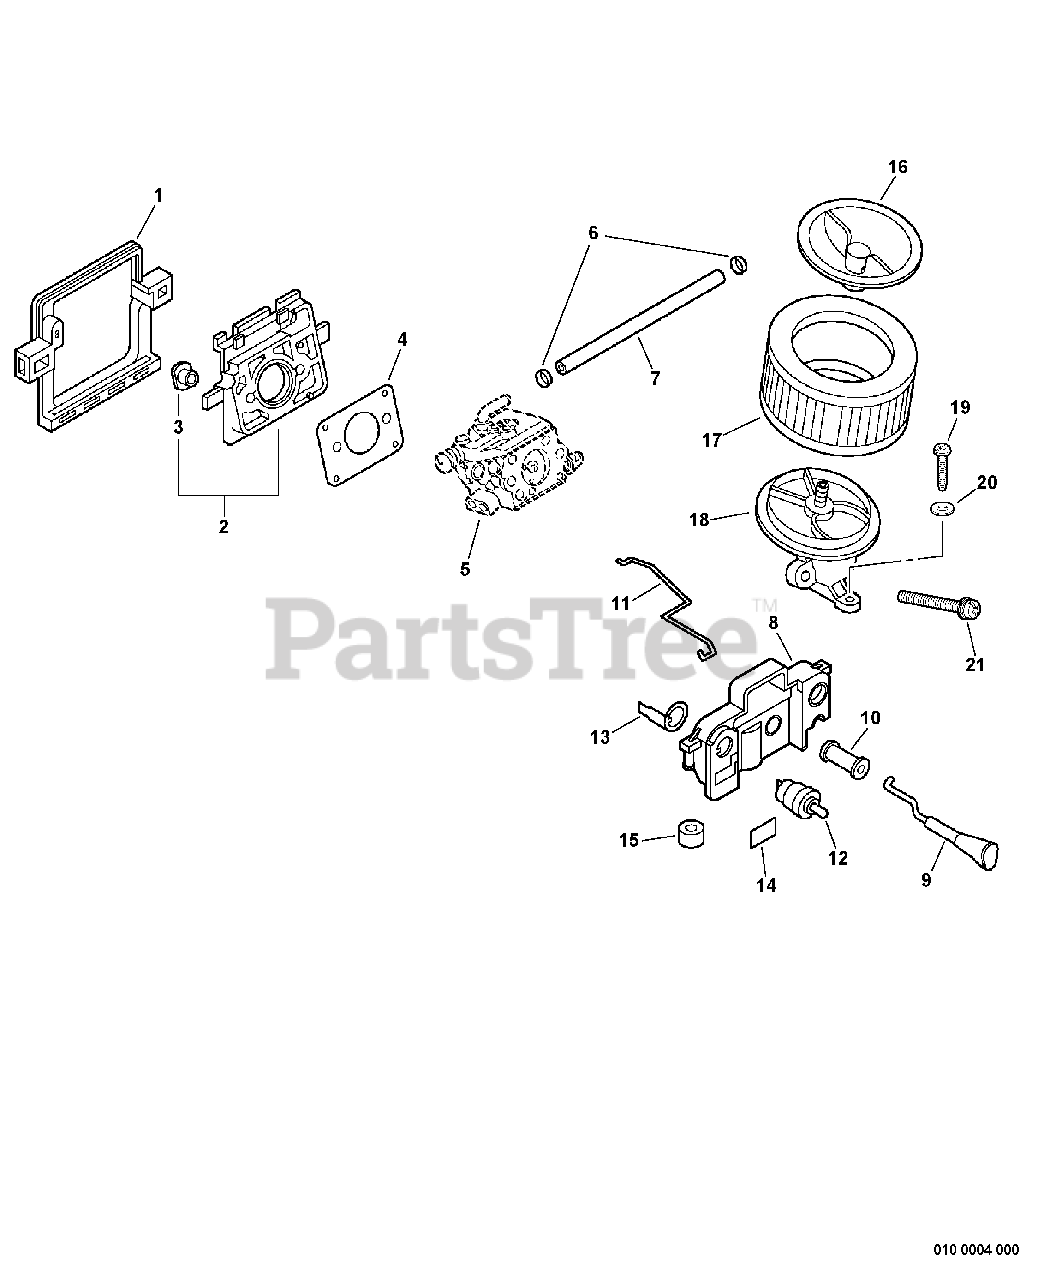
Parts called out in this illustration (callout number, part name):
1	CUSHION
2	INSULATOR
4	GASKET, INTAKE
5	CARBURETOR
6	CLIP 6 MM
7	PIPE, PULSE 2.4×6×105
8	BRACKET, SWITCH
9	ROD, CHOKE
10	GROMMET, CHOKE
11	ROD, THROTTLE
12	SWITCH, ON-OFF
13	TERMINAL - GROUND
14	LABEL, STOP
16	COVER, AIR FILTER
17	FILTER, HEAVY-DUTY AIR
18	ADAPTER, INTAKE
19	SCREW, TAPPING 5×20
20	WASHER, FLAT 5.5×10×0.8
21	SCREW 5×45
